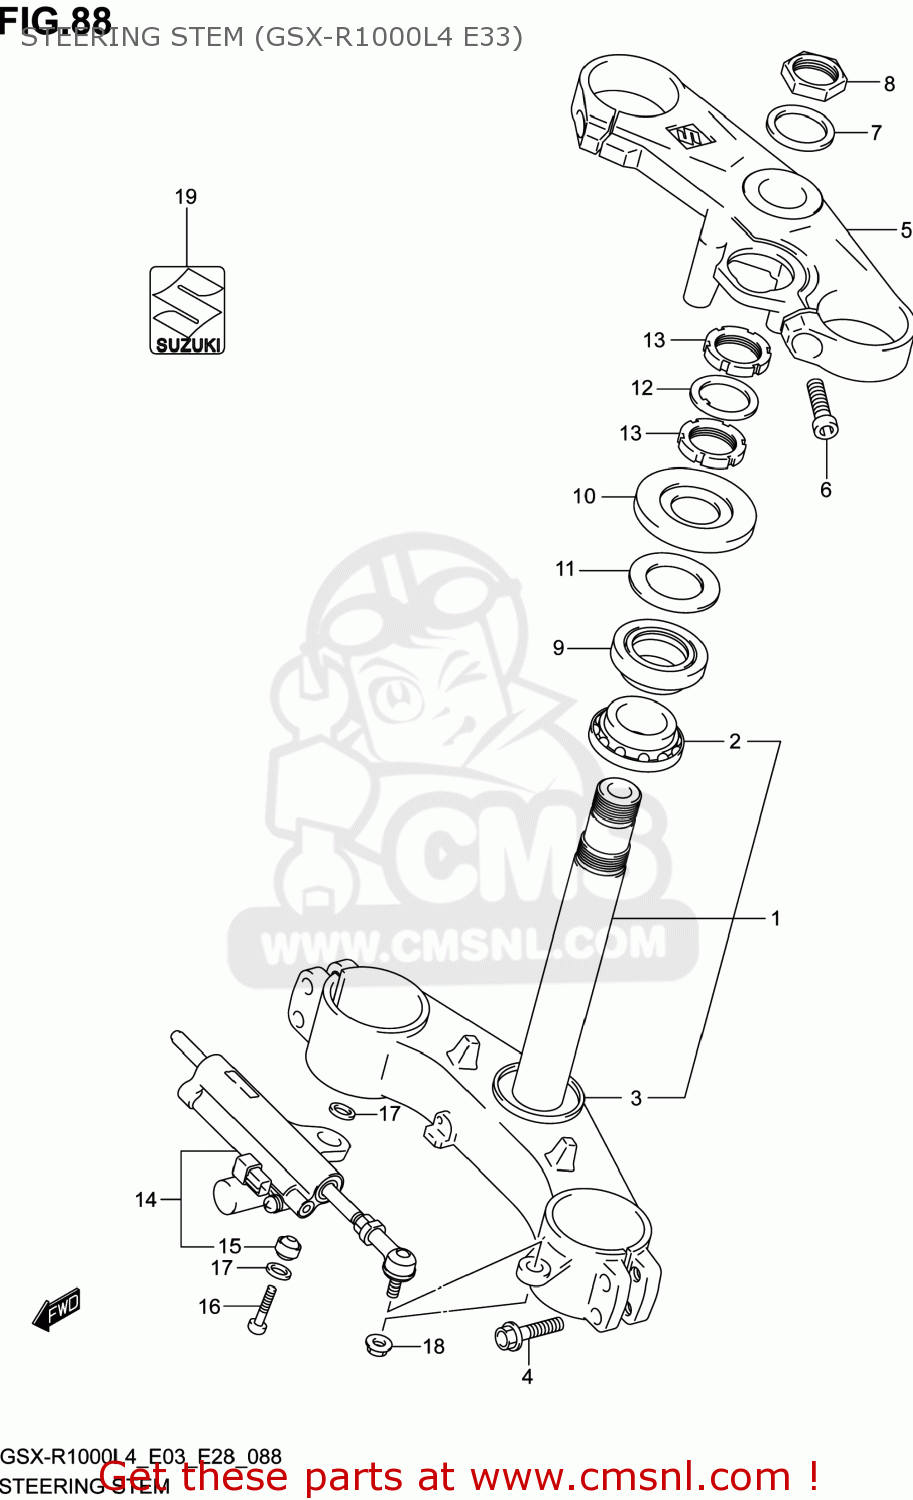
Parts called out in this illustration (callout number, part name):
1	STEM,STEERING
2	BEARING(30X55X17)
3	SEAL,STEERING LWR
4	BOLT,HOLDER AXLE(8X40)
5	HEAD,STEERING STEM
6	BOLT,HOLDER(8X25)
7	WASHER,STEM HEAD
8	NUT,STEM HEAD
9	BEARING(30X55X17)
10	COVER,STEERING UPR
11	SEAL,STEERING LWR
12	WASHER,STEERING STEM
13	NUT,STEERING STEM
14	DAMPER ASSY,STEERING
15	BEARING(8X17.5X11)
16	BOLT(8X35)
17	SEAL,PILLOW BALL,DUST
18	NUT
19	EMBLEM,"S"
